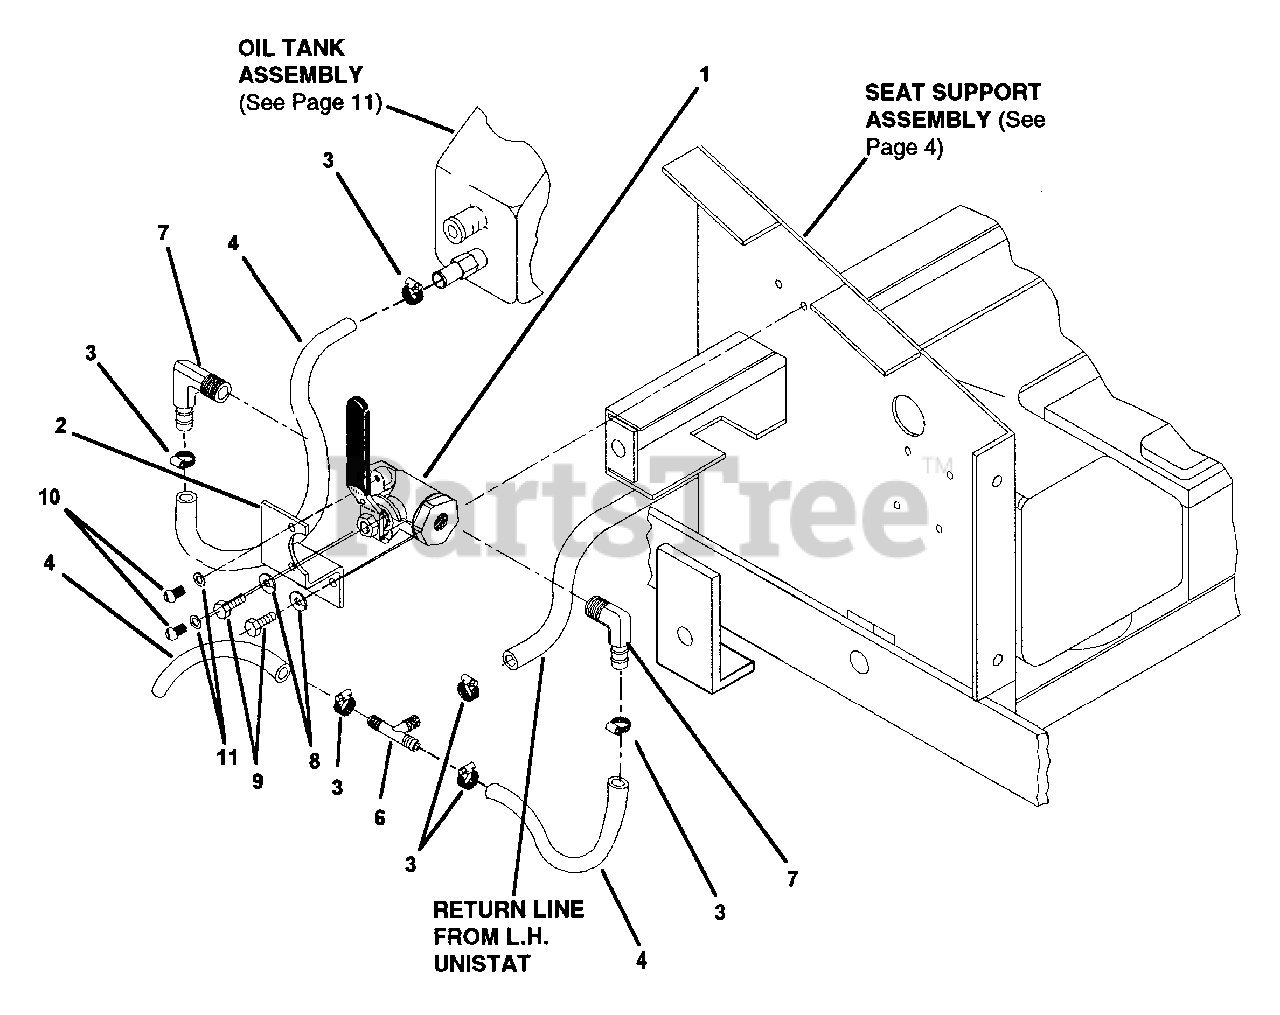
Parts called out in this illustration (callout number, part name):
1	BALL VALVE, 1/4 NPTF
2	BRACKET, BRAKE VALVE MTG.
3	HOSE CLAMP, 1/4 HH SCREW 1/4 MIN.
4	HOSE, 3/8 ID X 15" LONG
6	TEE, HOSE BARB, 3/8 X 3/8 X 3/8
7	HOSE BARB 90 EL 1 /4 NPTM X 3/8
8	LOCK WASHER, 1/4 EXTERNAL STAR
9	SCREW, 1/4 X 3/8 SELF-TAP
10	SCREW, #10-24 X 5/16, RND HEAD
11	LOCK WASHER SPLIT STL, # 10-32
